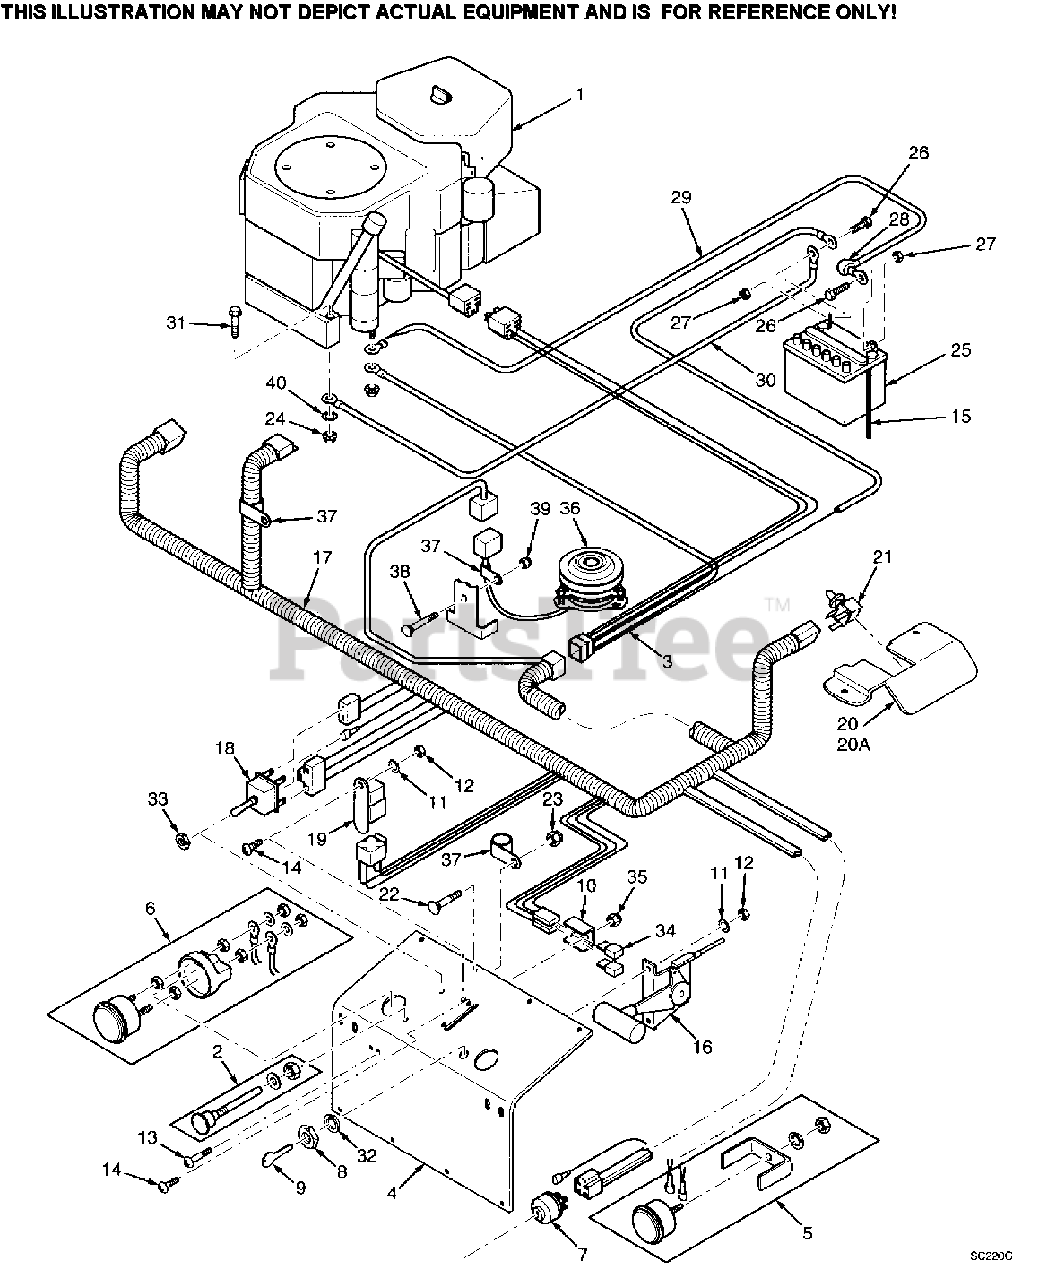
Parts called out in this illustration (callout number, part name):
2	CHOKE CONTROL
3	ADAPTER
4	KICK PLATE
5	HOUR METER
6	AMMETER
7	KEY SWITCH(INCLUDES MOUNTING HARDWARE)
8	NUT, HEX 5/8-32
9	KEY & RING ASSEMBLY
10	BRACKET, FUSE HOLDER
11	LOCKWASHER, #10 EXTERNAL TOOTH
12	NUT, HEX #10-32
13	SCREW, PHILLIPS WASHER HEAD #10-32 X 1-1/2"
14	SCREW, PHILLIPS WASHER HEAD #10-32 X 1/2"
15	OVERFLOW TUBE
16	THROTTLE CONTROL
17	WIRE HARNESS
18	SWITCH, MOWER ENGAGEMENT ELECTRIC CLUTCH
19	RELAY
20	NEUTRAL LOCK BRACKET, RH
20A	NEUTRAL LOCK BRACKET, LH
21	SWITCH NEUTRAL LOCK
22	BOLT, CARRIAGE 5/16-18 X .75"
23	NUT, ELASTIC STOP 5/16-18
24	NUT, SERRATED FLANGE HEX 5/16-18
25	BATTERY
26	BOLT, HEX HEAD 1/4-20 X 1/2"
27	NUT, HEX 1/4-20
28	RUBBER BOOT
29	BATTERY CABLE, 25" RED
30	BATTERY CABLE, 27" BLACK
31	BOLT, SERRATED FLANGE HEX HEAD 5/16-18 X
32	LOCKWASHER, 5/8" INTERNAL
33	NUT, HEX 1/2-27
34	FUSE, BLADE TYPE 20 AMP
35	NUT, ELASTIC STOP #10-32
36	ELECTRIC CLUTCH
38	BOLT, CARRIAGE 5/16-18 X 3/4"
39	NUT, ELASTIC STOP 5/16-18
40	LOCKWASHER, 5/16" INTERNAL TOOTH
